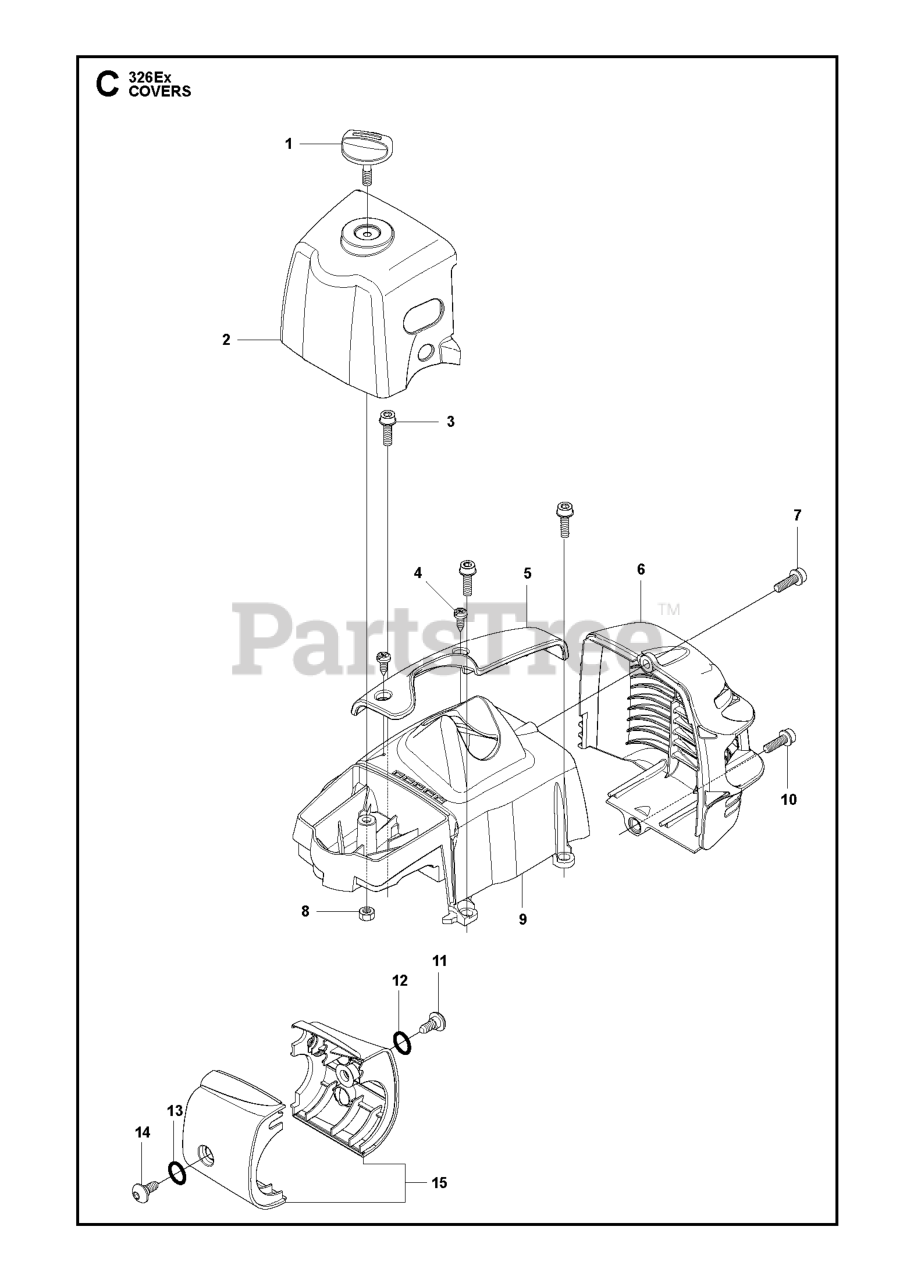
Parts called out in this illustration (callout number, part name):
2	FILTER COVER
3	SCREW
5	ARM PROTECTION
6	RP HEAT PROTECTOR
7	SCREW
10	RP CYLINDER COVER
12	SCREW MT5X11
13	O-RING 8X1.6
14	O-RING 8X1.6
